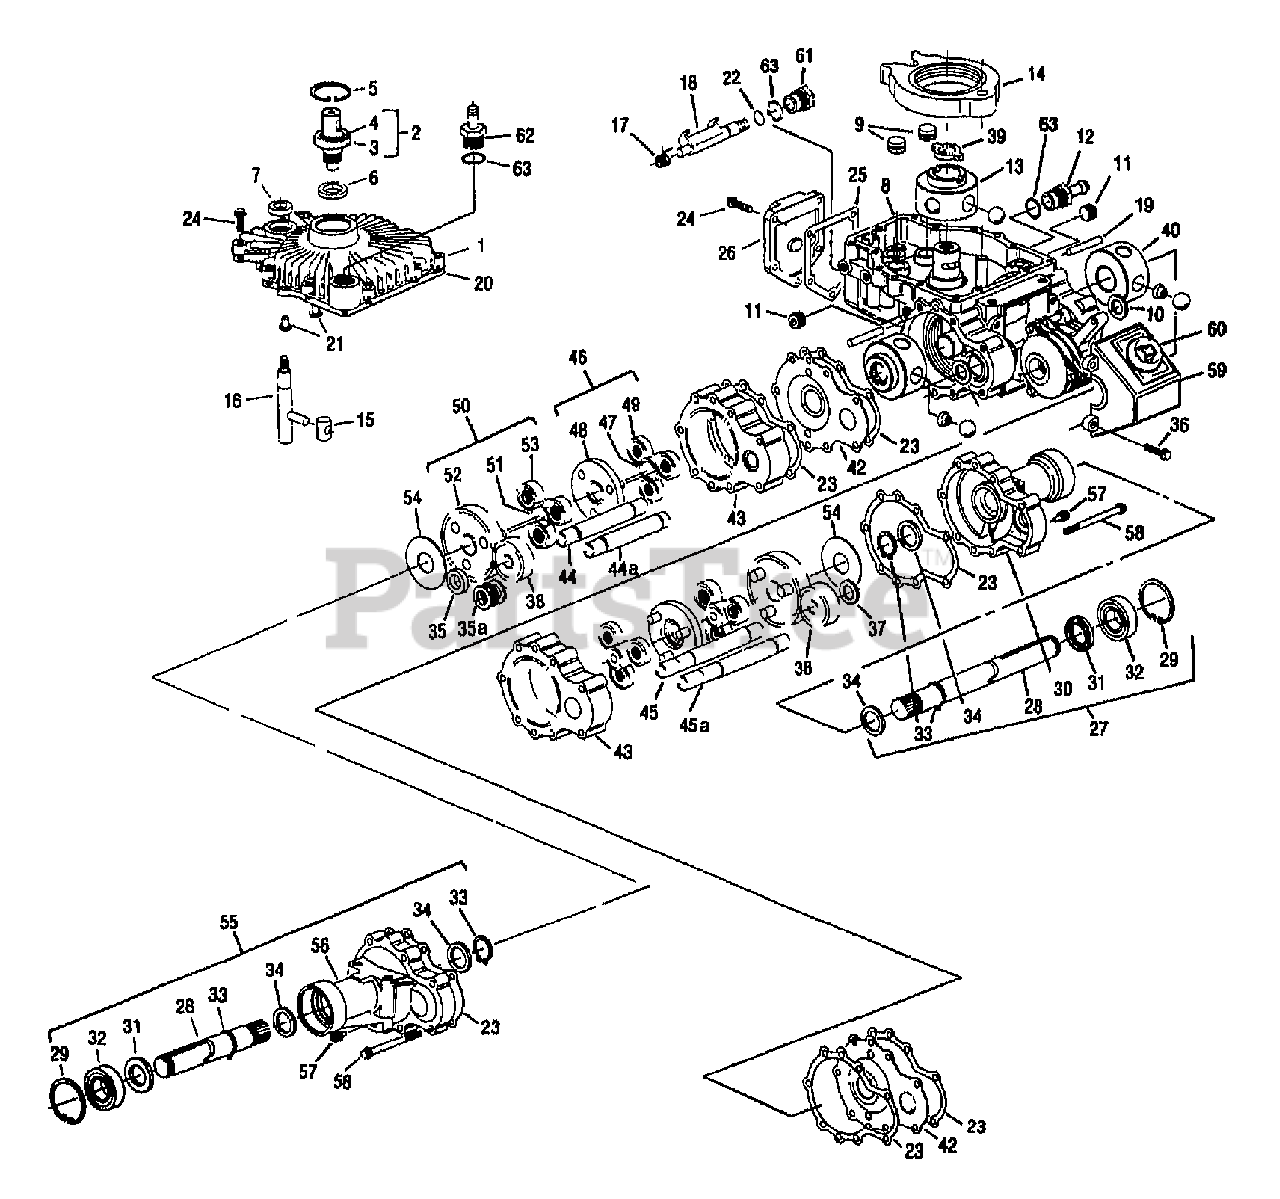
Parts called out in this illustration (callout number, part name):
1	COVER-TRANS AXLE
2	ASSM-SHAFT & BRG
5	RING-RETAINING INTERNAL
6	SEAL-OIL
7	SEAL-CONTROL SHAFT
8	HOUSING-S/A CW
9	PISTON-DAMPENING S/A
10	SHAFT-SEAL BRAKE
11	PIPE-PLUG SOCKET
12	TUBE-ADPT RESVR 3/8 ID
13	PUMP-ROTOR BALL S/A
14	RING-CAM S/A
16	SHAFT-CONTROL S/A
17	SPRING-DUMP VALVE
18	BRACKET
19	DOWEL
20	GASKET-COVER
21	BUTTON
22	RING-O
23	GASKET-AXLE HOUSING
24	SCR-.I4-20 HEX FLANGE
25	GASKET
26	COVER-VALVE
27	HOUSING-AXLE S/A-B
28	SHAFT-AXLE
29	RING-RETAINING INTERNAL
30	HOUSING-AXLE B
31	SEAL-AXLE AHAFT
32	BEARING
33	RING-RETAIN EXTERNAL
34	WASHER-THRUST
35	SPACER (THICK-PB)
35A	WASHER-THRUST (DL/PB)
36	SCR-1/4-20 SELF TAP
37	SPACER (THIN PB OR DL/PB)
38	GEAR-BRAKE
39	DRIVE
40	MTR RTR-BALL S/A A&B 18T
42	PLATE-WEAR
43	RING-GEAR S/A A&B 54T
44	SHAFT-BRAKE A (PB)
44A	SHAFT-BRAKE A (DL/PB)
45	SHAFT-BRAKE B (PB)
45A	SHAFT-BRAKE B (DL/PB)
46	PLANETARY GR 1ST S/A A&B
48	PRIMARY CARRIER
49	PINT. GEAR
50	PLANETARY GR 2ND S/A A&B
52	CARRIER-SECONDARY
53	PINT. GEAR
54	WASHER-THRUST
55	HOUSING-AXLE
56	HOUSING-AXLE A
57	PLUG-MAGNETIC
58	SCR-1/4-20 HEX FLANGE
59	COVER (PB OR DL/PB)
60	BOOT-DUST
61	NUT-DUMP VALVE
62	ADPT-RESVR 3/8 ID TUBE
63	RING-O
